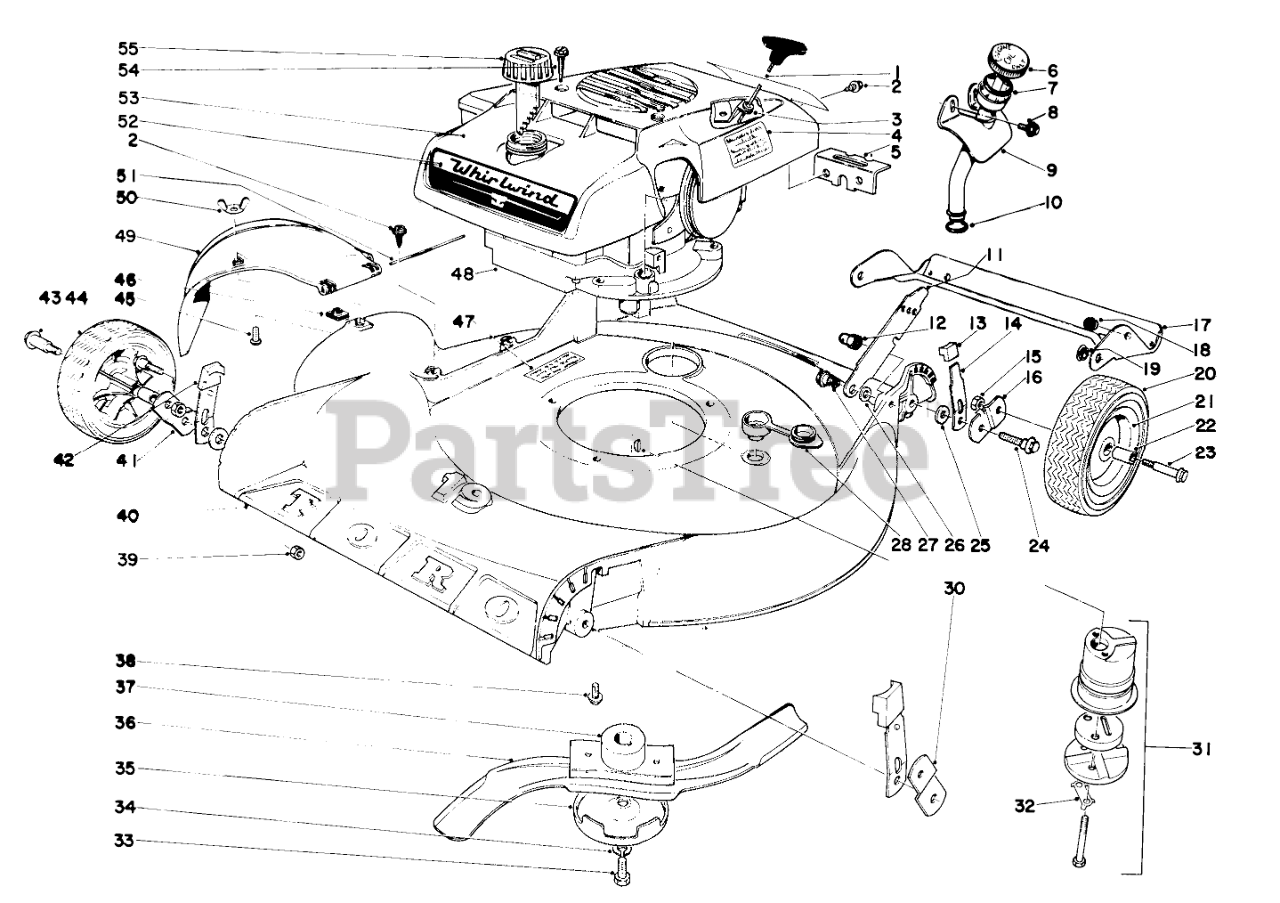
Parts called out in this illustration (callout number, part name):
1	Decal,Maintenance
2	SCREW-HWHTF
3	Bracket,Recoil
4	Decal,Start
5	Bracket
6	Dipstick
7	O-Ring
9	Oiler Tube
10	O-RING
11	Latch
12	Nut
14	Spring Arm
15	Nut
16	Pivot Arm
17	Rear Safety Shield (Incl. Ref. 18) (Model 18400)
18	SKID BUTTON
19	Nyliner
20	8 TIRE
21	Wheel (Incl. Ref. 22)
22	Bushing
23	Wheel Bolt
24	Pivot Screw
25	WASHER-PIVOT
26	SPACER
27	SCREW-SHOULDER
28	Washer Plug
29	KEY-WOODRUFF
30	Pivot Arm
31	Model (Incl . Ref. No. 32)
32	CLIP - LOCKING
33	SPECIAL SCREW
34	WASHER-LOCK
35	ANTI-SCALP CUP
36	Blade
37	BLADE RETAINER WA
38	SCREW-HWHTF
39	Nut
40	Housing
41	Pivot Arm
42	ARM KNOB
46	NUT-SPEED
47	Decal
48	Engine, Model 18400
49	Deflector
50	NUT-WING SPECL
51	HINGE PIN
52	Decal
53	Shroud
54	SCREW-HWH
55	Gas Cap
